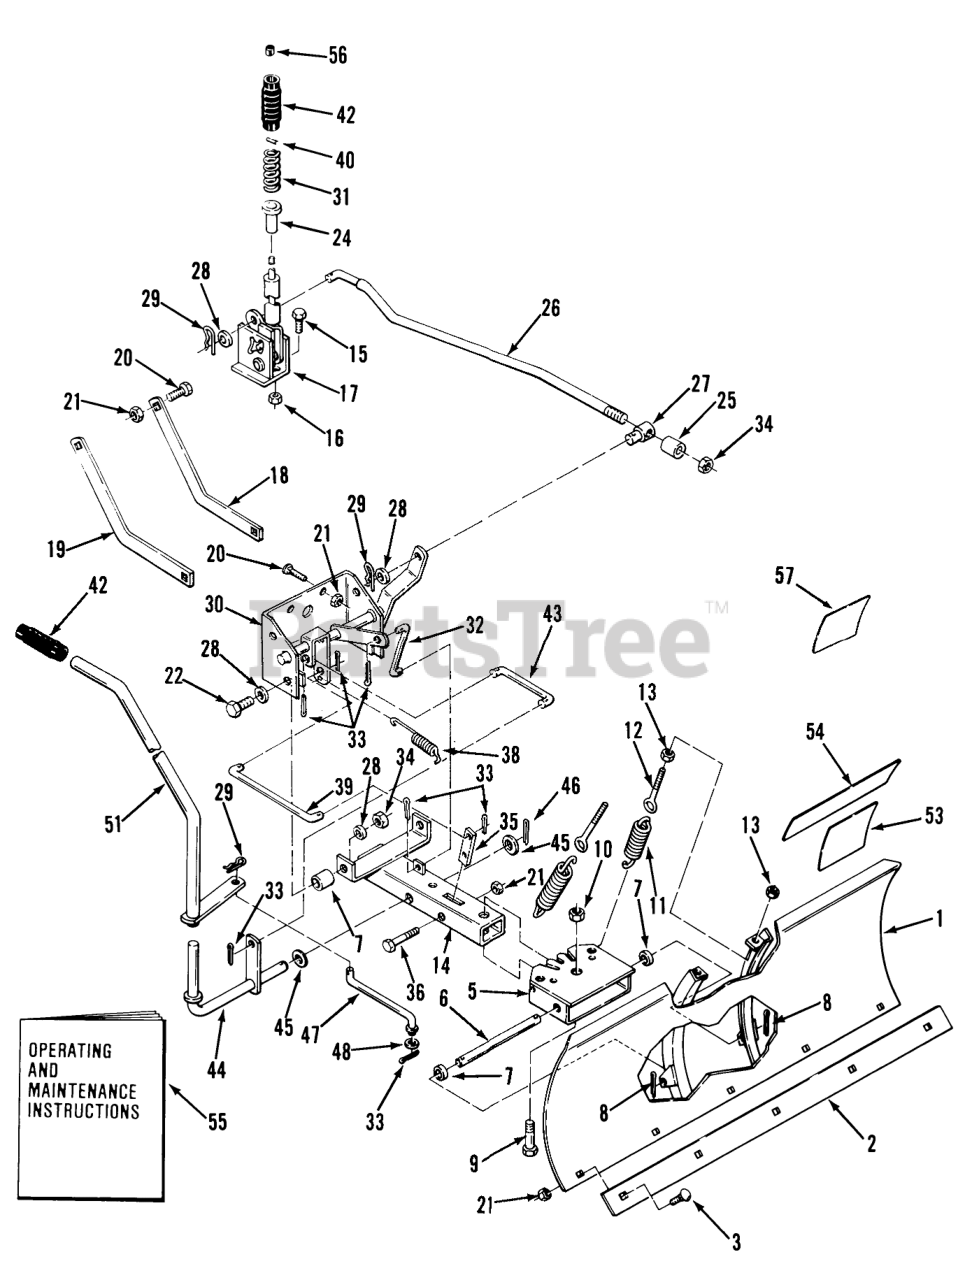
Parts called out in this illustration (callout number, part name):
1	Blade
2	Plate
3	Bolt-Carriage
5	ASSY-QUADRANT R
6	ROD-LOWER
7	Spacer
9	HEX HD CAP SCREW
10	Nut
11	SPRING
12	EYEBOLT
13	Nut
14	ASS'Y-FRAME R
15	Bolt-Carriage
16	Nut
17	ASS'Y-LIFT HANDLE R
18	BRACE-RH R
19	Brace-RH
20	Bolt
21	NUT
22	H H C S
24	RETAINER-SPRING
25	Spacer
27	TRUNION
28	Washer
29	Hairpin
30	ASS'Y-BELLCRANK L R
31	SPRING-COMPRESSION
32	Rod
33	Pop Rivet
34	Nut
35	LATCH-QUADRANT R
36	HHCS
38	SPRING
39	ROD-LATCH
40	PIN-SPIROL
42	HANDGRIP
43	ROD-BELLCRANK
44	Handle Pivot
45	Washer
46	Cotter Pin
47	ROD-ANGLING
48	Washer
51	ASSY-HANDLE R
53	DECAL-CAUTION
54	DECAL WHEEL HORSE
55	Operating and Maintenance Instructions
56	CAP-ROD, PLUNGER
57	DECAL-OVERLAY
